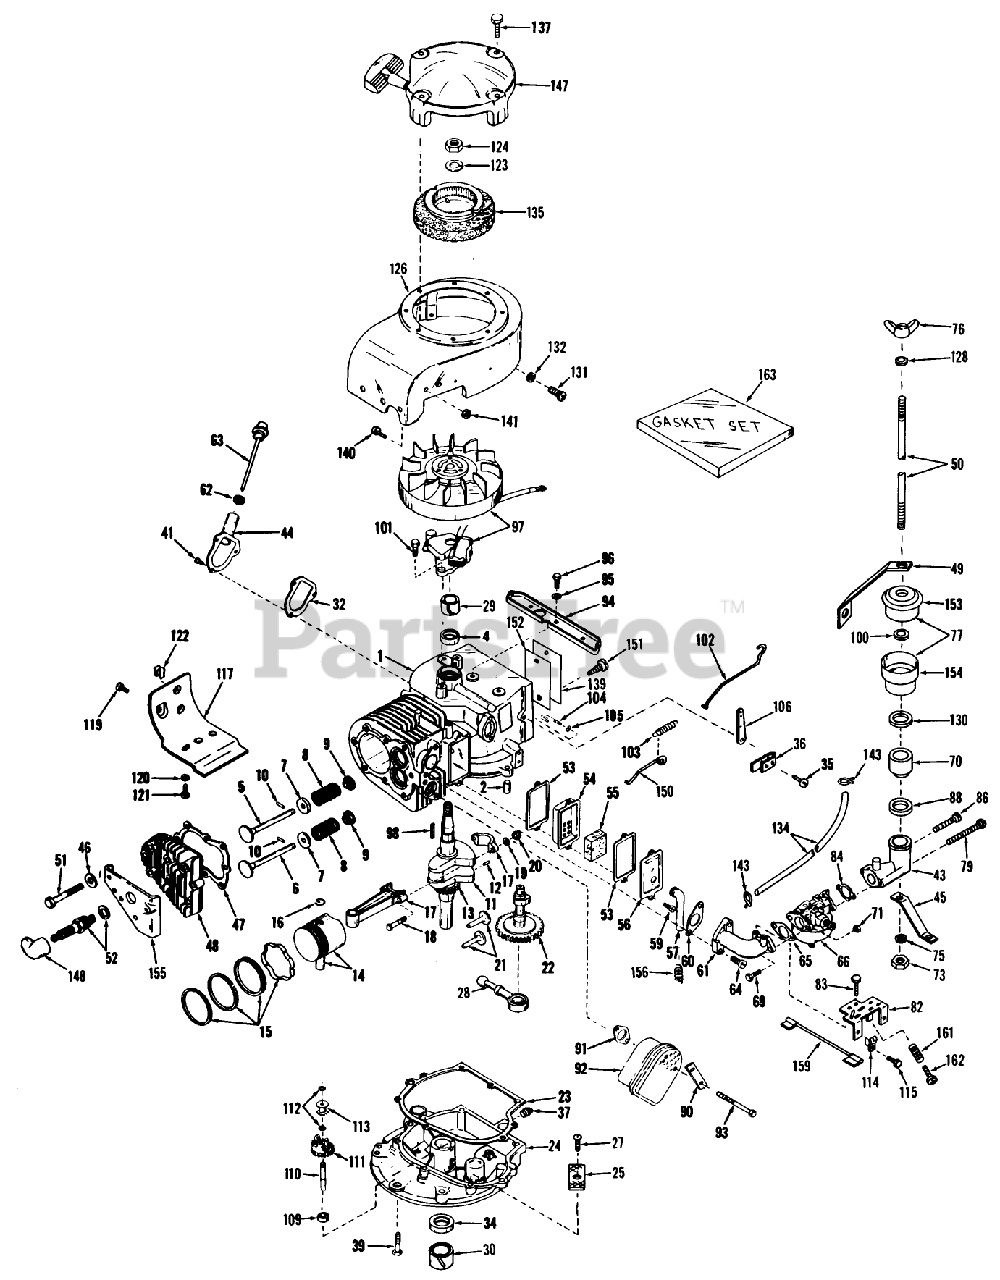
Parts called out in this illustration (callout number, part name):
1	Cylinder Assy.(Incl. Nos. 2 4)
2	Pin-Dowel
4	Seal, Oil
5	Valve, Intake (Standard)
5	Valve, Intake (1/32" oversize)(Incl. Ref. No.9)
6	Valve, Exhaust (Standard)
6	Valve, Exhaust (1/32" overs.)(Incl. Ref. No.9)
7	Cap-Spring, Valve
8	Spring-Valve
9	Cap, Lower valve spring
9	Cap, Lower Valve Spring (1/32" oversize)
10	Pin, Valve spring retaining
11	52038A RIDING MWR W
11	Crankshaft Assy 34" Whirlwind only
12	Pin, Groove
13	Gear-Crankshaft
14	Piston Pin Assy., Std., (Incl. 2 of No. 16)
14	Piston Pin Assy., .010 oversize (Incl. 2 of No. 16)
14	Piston Pin Assy., .020 oversize (Incl. 2 of No. 16)
15	Clevis Pin
15	Ring Set, Piston (.010 oversize)
15	Ring Set, Piston (.020 oversize)
17	Rod Assy., Connecting (Incl. Nos.18,19 20)
17	Rod Assy., Connecting (Incl. Nos. 18, 19 20)(Model V60-70073G only)
18	Bolt, Connecting Rod
19	Washer
21	Lifter Valve
22	Camshaft
23	Gasket-Cover, Cylinder
24	Flange Assy., Mounting (Incl. Nos. 25, 27, 30, 34, 37 110)
25	Screen-Oil Filter
27	Screw
28	Pump, Oil
29	Bushing, Crankshaft
30	Bushing, Crankshaft
32	Gasket, Filler tube
34	Seal-Oil
35	Screw
36	Clamp-Lever, Governor
37	Plug-Drain, Oil (SQH 1/4-18)
39	Screw (1/4-20 x 1-1/4)
41	Screw
43	Elbow, Air cleaner
44	Tube, Oil Filler
45	Brace, Cleaner elbow
46	Washer
47	Gasket-Head, Cylinder
48	CYLINDER HEAD
49	Brace Cleaner
50	Stud, Air cleaner
51	Screw
52	SPARK PLUG
53	Gasket-Breather
54	Body-Breather
55	Element-Breather
56	Cover-Valve
57	Tube-Breather
59	Screw
60	Gasket-Intake
61	Pipe, Intake
62	Gasket
63	Dipstick, Oil (Incl. No. 62)
64	Screw (T-30, 5/16-18x1-3/32)
65	Gasket
66	Carburetor
70	Spacer, Cleaner
71	Nut and Lock Washer (1/4-28)
75	Lockwasher, Split
76	Nut-Wing
77	Cleaner Assy., Oil Bath Air (Incl. Nos.100,128,130,153 154)
79	Screw
82	Control Assy., Speed
83	Screw (10-24 x 9/16)
84	Gasket
86	KIT - SEAL WIPER
88	Gasket, Spacer
90	62513 SNWTHWR W/284
91	Gasket Exhaust
92	Muffler
93	Screw
94	Bracket, Blower Housing (Incl. Nos. 131)
95	Lockwasher
96	Screw
97	Magneto
98	Key, Flywheel
100	O Ring
101	Screw
102	Link Governor
103	Spring Governor
104	Rod, Governor (Incl. Nos. 146)
105	Washer-Flat
106	Lever-Governor
109	Spacer
110	Shaft, Governor
111	Governor Gear ASM
112	Ring-Retaining
113	Spool-Governor
114	Conduit
115	Screw (10-32 x 3/8)
117	Emnsion, Blower Housing
119	Screw
120	Lockwasher
121	Screw
122	51004 GIL ROTARY TI
123	Washer
126	Housing, Blower
128	Washer
130	1565F GIL TILLER.AD
131	Screw
132	Lockwasher
134	Line-Fuel
135	Hub Screen
137	Screw
139	480B GIL SNWTHWR O/
140	Screw
141	Nut-Jam (5/16-24)
143	Clamp-Line, Fuel
147	Starter, Rewind
148	Cover-Spark Plug
150	Link, Governor spring
151	Stud
152	IDENTIFICATION PLATE
153	Cover, Oil bath cleaner
154	Bowl, Oil Bath Cleaner
155	Cover, Cylinder head
156	Spring, Coil
159	Wire, Ground
161	Spring-Compression
162	Screw
163	Gasket Set
